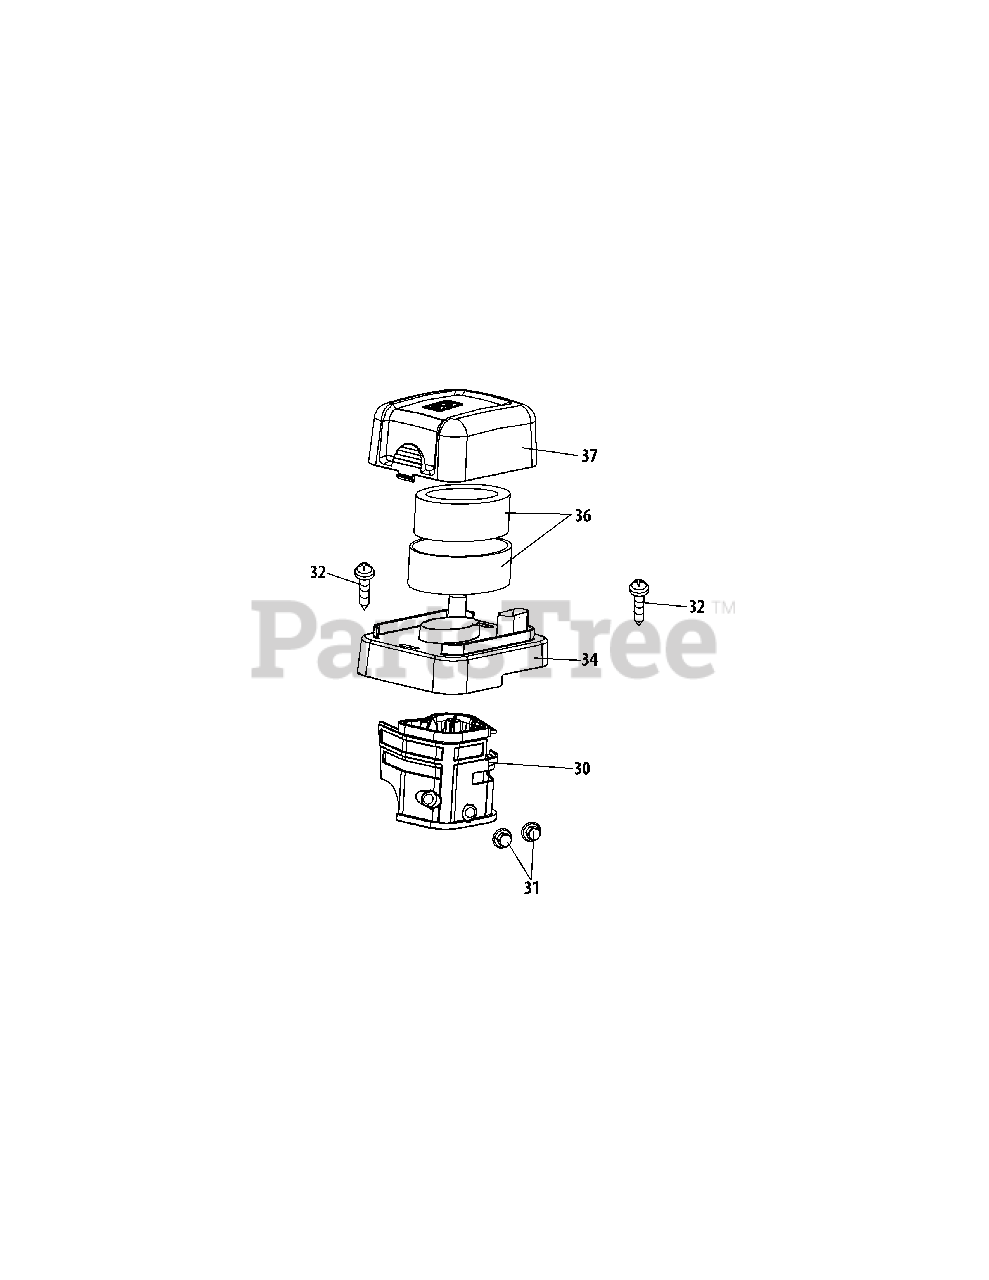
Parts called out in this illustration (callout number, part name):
30	Air Filter Heating Pipe Base
32	Self-Tapping Bolt M4.2×16
34	Air Filter Base
36	Air Cleaner Filter Assembly
37	Air Cleaner Cover
